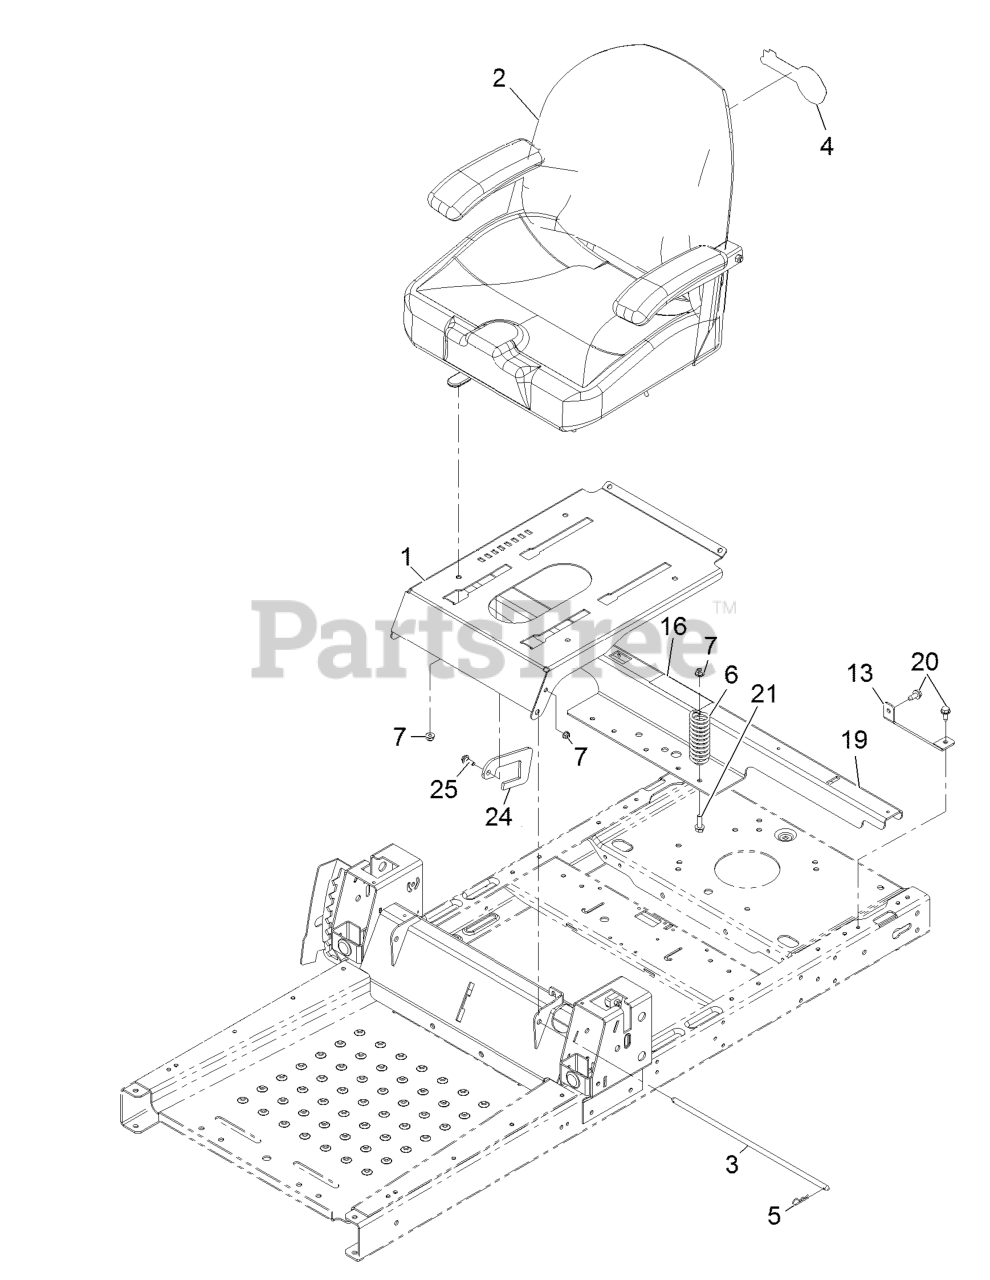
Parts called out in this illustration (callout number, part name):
2	SEAT ASM
3	ROD-STOP
5	PIN-COTTER
6	SPRING-COMPRESSION
7	NUT-HF, NI
13	SUPPORT-TANK, REAR
16	DECAL-SERVICE, CE
19	SUPPORT-POD
20	Screw-HWH 5/16-18 X 3/4 Tf
21	SCREW-HHF
24	STOP-SEAT
25	SCREW-SHOULDER
